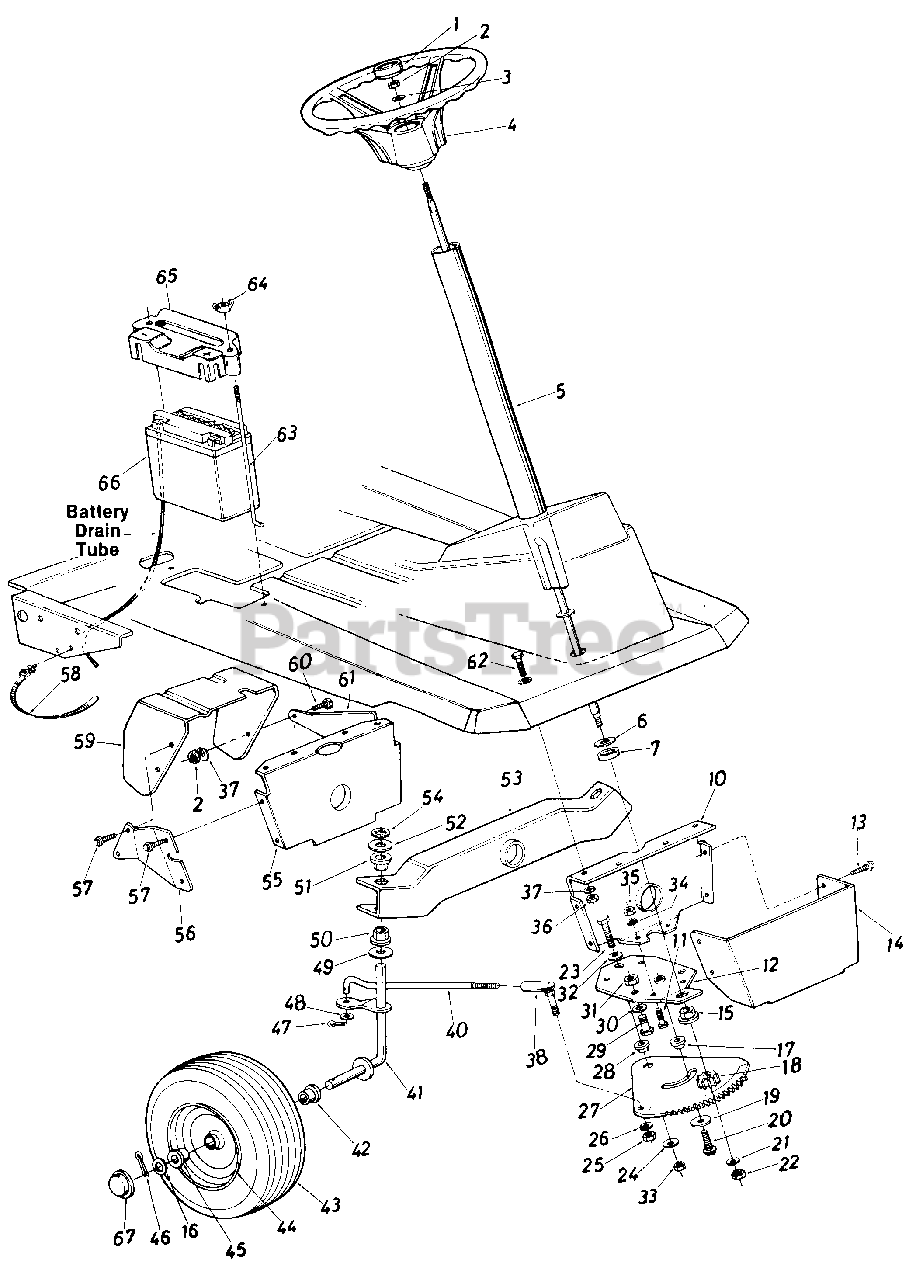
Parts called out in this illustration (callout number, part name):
1	Steering Wheel Cap
2	Hex Nut 5/16-18 Thd.*
3	Bell-Wash. .345" I.D. x .88" O.D.
4	Steering Wheel Ass'y.
5	Steering Shaft Ass'y.
6	FI Wash. .62" I.D. x 1.50" O.D.
7	Spacer (Plastic)
10	Pivot Bar Bracket
11	Hex Bolt 5/16-18 x .75" Lg.*
12	Steering Gear Support Brkt.
13	Hex Wash. Hd. AB-Tap Scr. 1/4 x.62" Lg.
16	Fl-Wash. .64" I.D. x 1.62 O.D.
17	Shoulder Spacer .622 Dia. x .21 8
18	Steering Pinion Gear
19	Fl-Wash. .385" I.D. x 1.38" O.D.
20	Hex Wash. Hd. Self-Tap Scr. 3/8-16 x 1.25" Lg.
21	Bell-Wash. .345" I.D. x .88" O.D.
22	Hex Nut 5/16-24 Thd.*
23	Hex Bolt 3/8-24 x 1.25" Lg. (Grade 5)
24	Fl-Wash. .385" I.D. x 1.38" O.D.
25	Hex Nut 3/8-24 Thd.*
26	L-Wash. 3/8" I.D.*
27	Steering Gear Segment
28	Shoulder Spacer .622" Dia. x .218
29	Hex Bolt (Nylon) 1/2-13 x .75" Lg.
30	Fl-Wash. .530" I.D. x .930" O.D.
31	Hex Nut 1/2-13 Thd.*
32	Bell-Wash. .385" I.D. x .88" O.D.
33	Hex Nut 3/8-24 Thd.*
34	L-Wash. 5/16" I.D.*
35	Hex Nut 5/16-18 Thd.*
36	Hex Nut 5/16-18 Thd.*
37	L-Wash. 5/16" I.D.*
38	Ball Joint Ass'y. 3/8-24 Thd.
40	Steering Tie Rod
41	Front Axle Ass'y. R.H.
42	Flange Bearing .632" I.D.
43	Front Wheel Ass'y. Comp.
44	Front Wheel Rim Only
45	Flange Bearing .632" I.D.
46	Cotter Pin 1/8" Dia. x 1.25" Lg.*
47	Cotter Pin 1/8" Dia. x 1.00" Lg.*
48	Fl-Wash. .385" I.D. x .87" O.D.
49	Fl-Wash. .635" I.D. x 1.12" O.D.
50	Hex Flange Bearing
51	Hex Flange Bearing
52	Fl-Wash. .635" I.D. x 1.12" O.D.
53	Pivot Bar Ass'y.
54	Speed Nut 5/8" I.D.
55	Pivot Bar Bracket
56	Bracket Reinforcement R. H .
57	Hex Wash. Hd. AB-Tap Scr. 1/4 x.62" Lg.
58	Cable Tie
59	Clutch-Brake Pedal Ass'y.
60	Hex Bolt 5/16-18 x .75" Lg.*
61	Bracket Reinforcement L.H.
62	Hex Bolt 5/16-18 x .75" Lg.*
63	Battery Hold Down Rod
64	Wing Nut Solid 1/4-20 Thd.
65	Battery Cover
66	12V Battery
